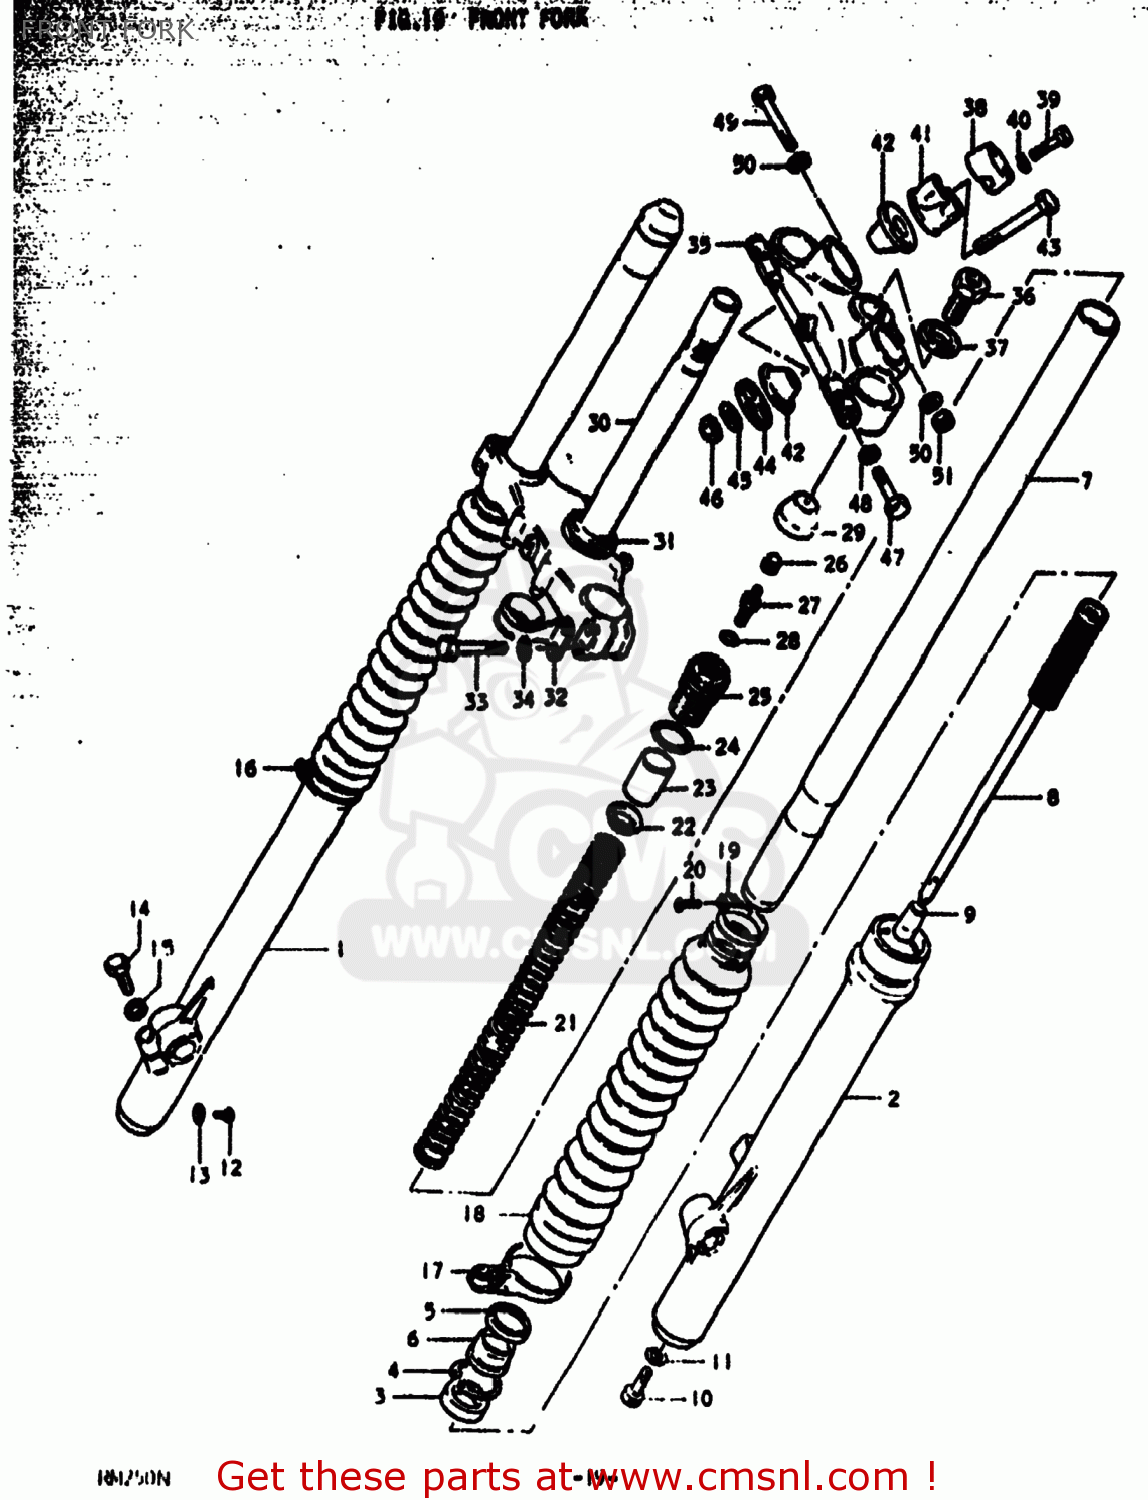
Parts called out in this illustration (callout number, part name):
1	TUBE,OUTER,RIGHT
2	TUBE,OUTER,LEFT
3	SEAL,OIL
4	CIRCLIP,FORK OIL SEAL
5	CASE,DUST SEAL FRONT FORK
6	DUST SEAL,FRONT FORK
7	TUBE,FORK,INNER
8	CYLINDER,FRONT FORK
9	PIECE,OIL LOCK
10	BOLT,CYLINDER
11	GASKET,CYLINDER (NAS)
12	SCREW
13	GASKET,DRAIN,PLUG (NAS)
14	BOLT (8X30)
15	LOCK WASHER
16	BAND,FRONT FORK COVER BOOT
17	BAND,FRONT FORK COVER BOOT
18	BOOT
19	BAND,BOOT
20	SCREW
21	SPRING
22	GUIDE
23	COLLAR,SPRING
24	O RING
25	CAP,FORK INNER TUBE
26	CAP,VALVE
27	VALVE
28	O RING
29	CAP
30	STEM,STEERING
31	RACE,STEERING,OUTER,UPPER
32	GUIDE,CABLE
33	BOLT 8X45
34	LOCK WASHER
35	HEAD,STEERING STEM
36	BOLT
37	WASHER
38	HOLDER,HANDLEBAR
39	BOLT
40	LOCK WASHER
41	HOLDER,HANDLEBAR,LOWER
42	CUSHION,HANDLE HOLDER
43	BOLT,HANDLE HOLDER
44	COVER,HANDLEBAR HOLDER
45	WASHER,HANDLEBAR HOLDER
46	NUT
47	BOLT
48	LOCK WASHER
49	BOLT 8X50
50	WASHER
51	NUT
